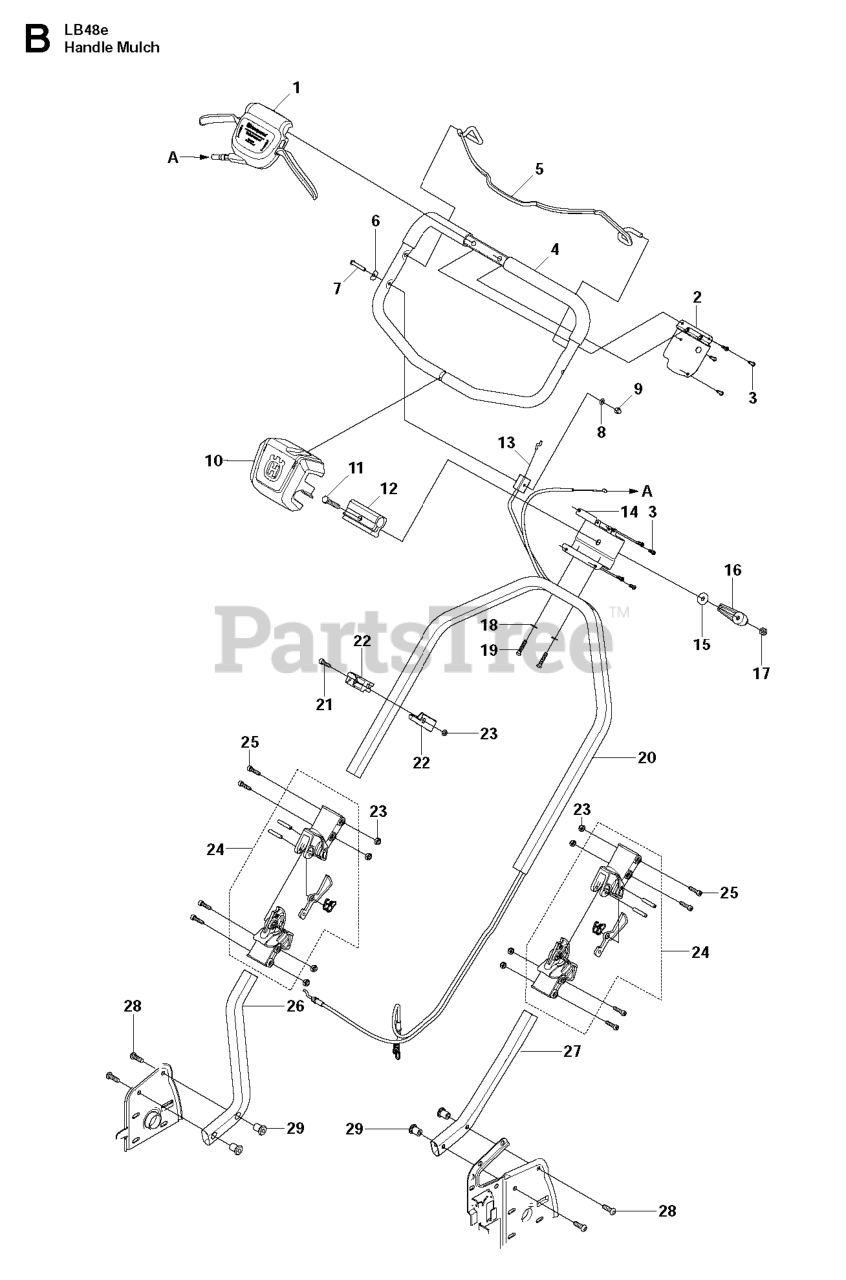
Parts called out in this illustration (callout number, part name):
8	WASHER - M6
15	WASHER - 25X8.5X2.3
21	SCREW MC6S 6X20
25	REPL BY 725 53 74-55
